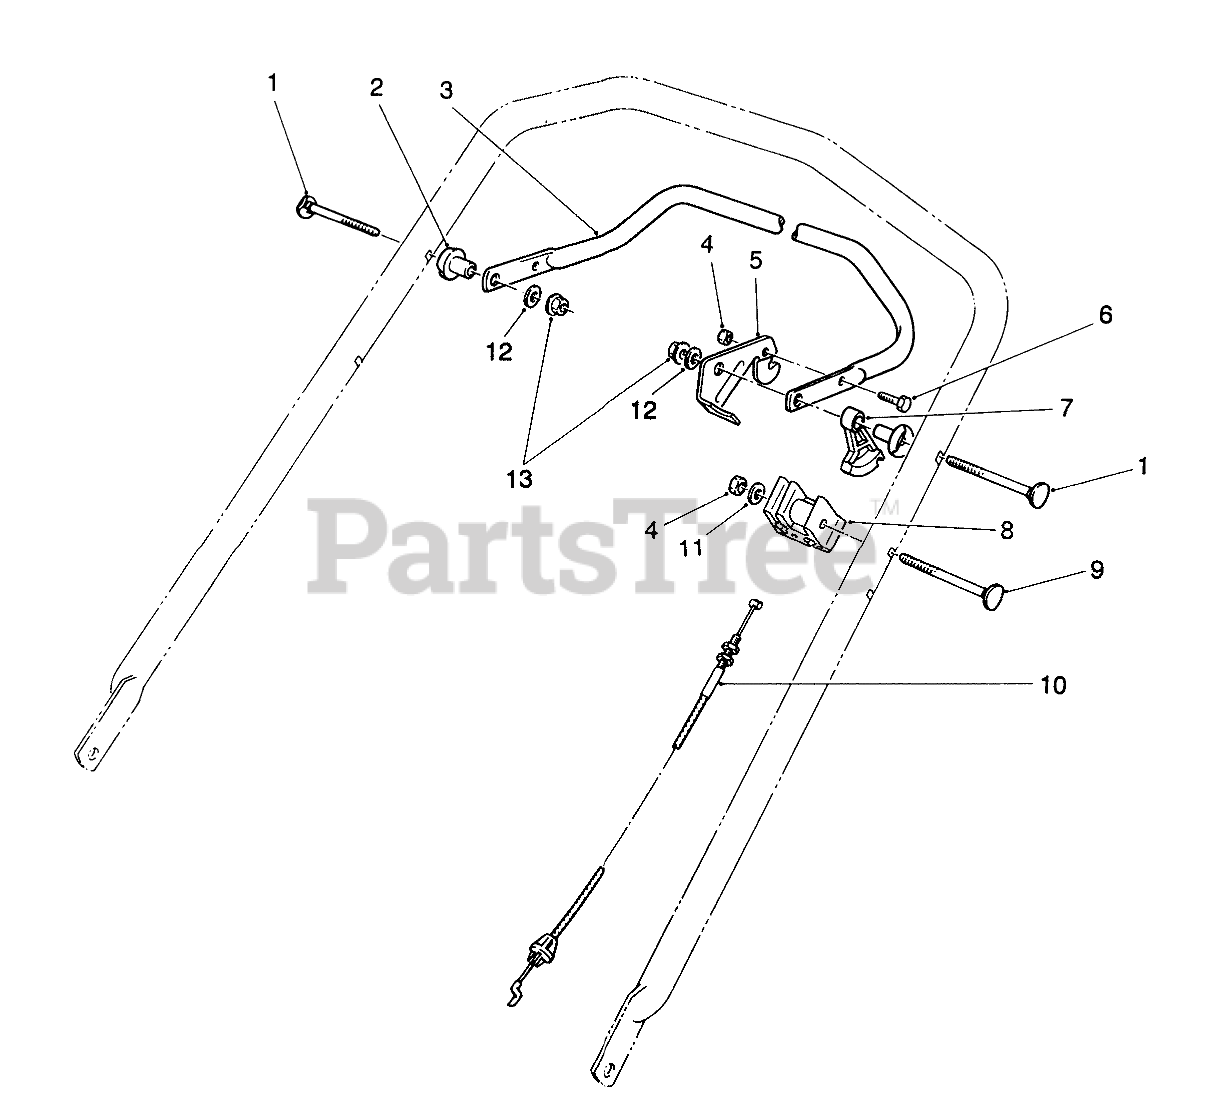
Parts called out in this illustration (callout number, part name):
1	SCREW-HANDLE
2	SPACER-SUPPORT
3	Bar-Control
4	NUT-LOCK, NI
5	CONTROL LEVER
6	SCREW-HH
7	LEVER-TRACTION
8	SUPPORT-CABLE
9	SCREW-HANDLE
10	TRACTION CABLE
11	WASHER-FLAT
12	WASHER-PLAIN
13	NUT-LOCK, NI
